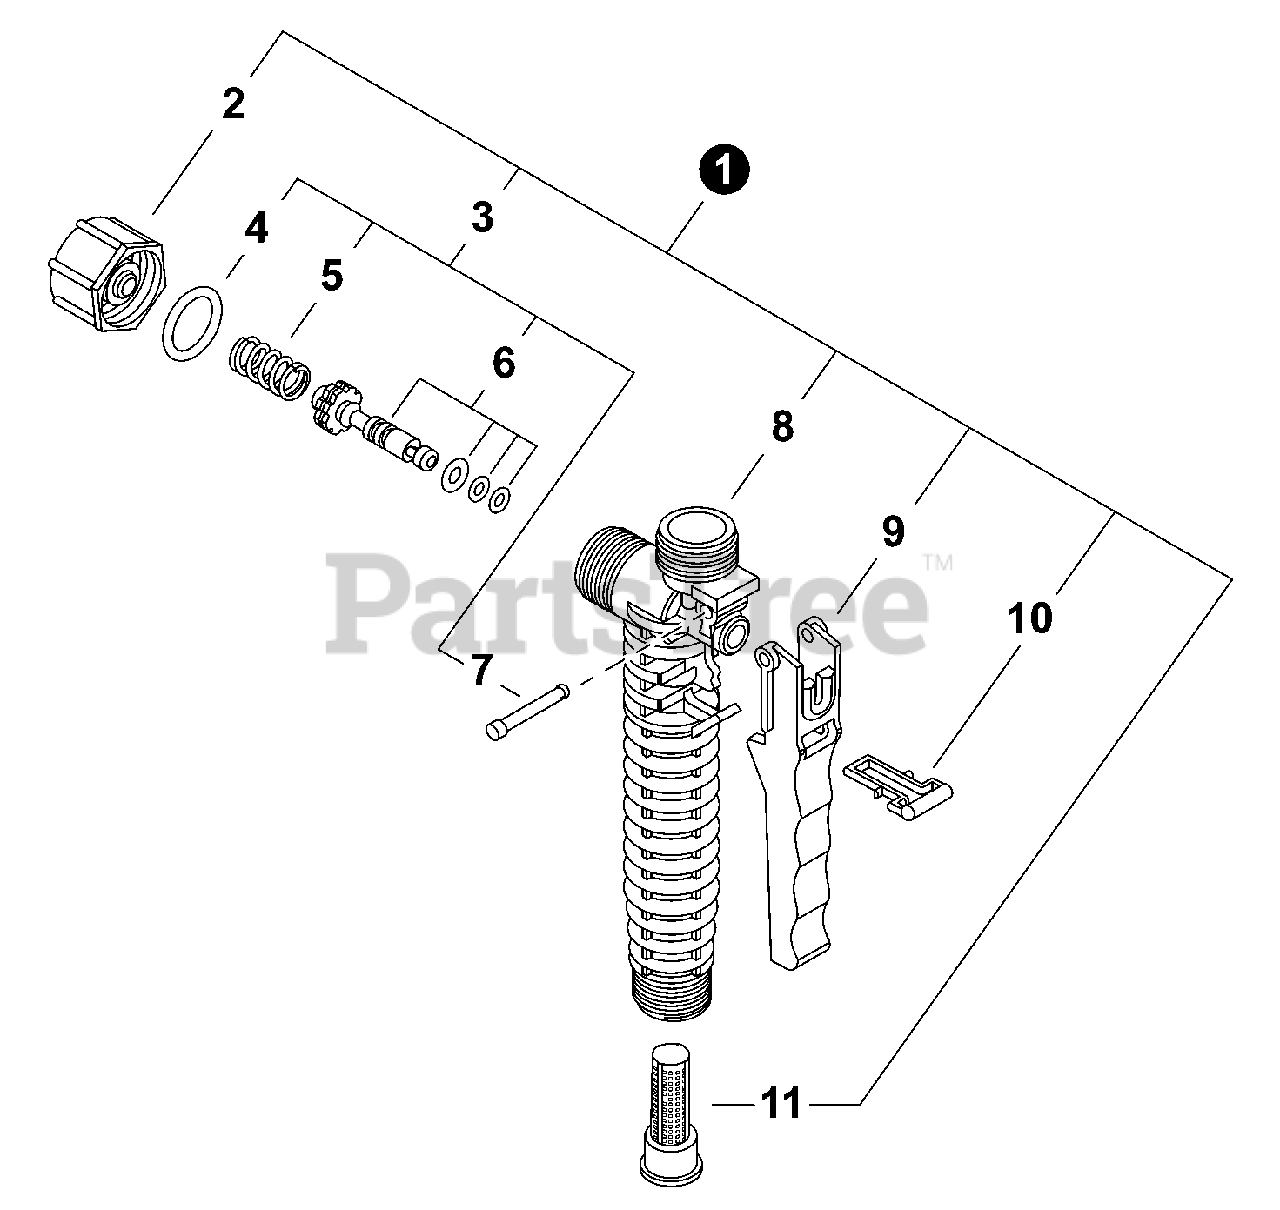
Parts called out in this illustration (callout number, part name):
1	GUN, SPRAY
2	CAP, DISCHARGE
3	REPAIR KIT, DISCHARGE
4	O-RING, DISCHARGE
5	SPRING, DISCHARGE
6	SPOOL ASSY
7	PIN, TRIGGER
8	BODY, SPRAY GUN
9	LEVER, TRIGGER
10	LOCK, TRIGGER
11	FILTER, SPRAY GUN
